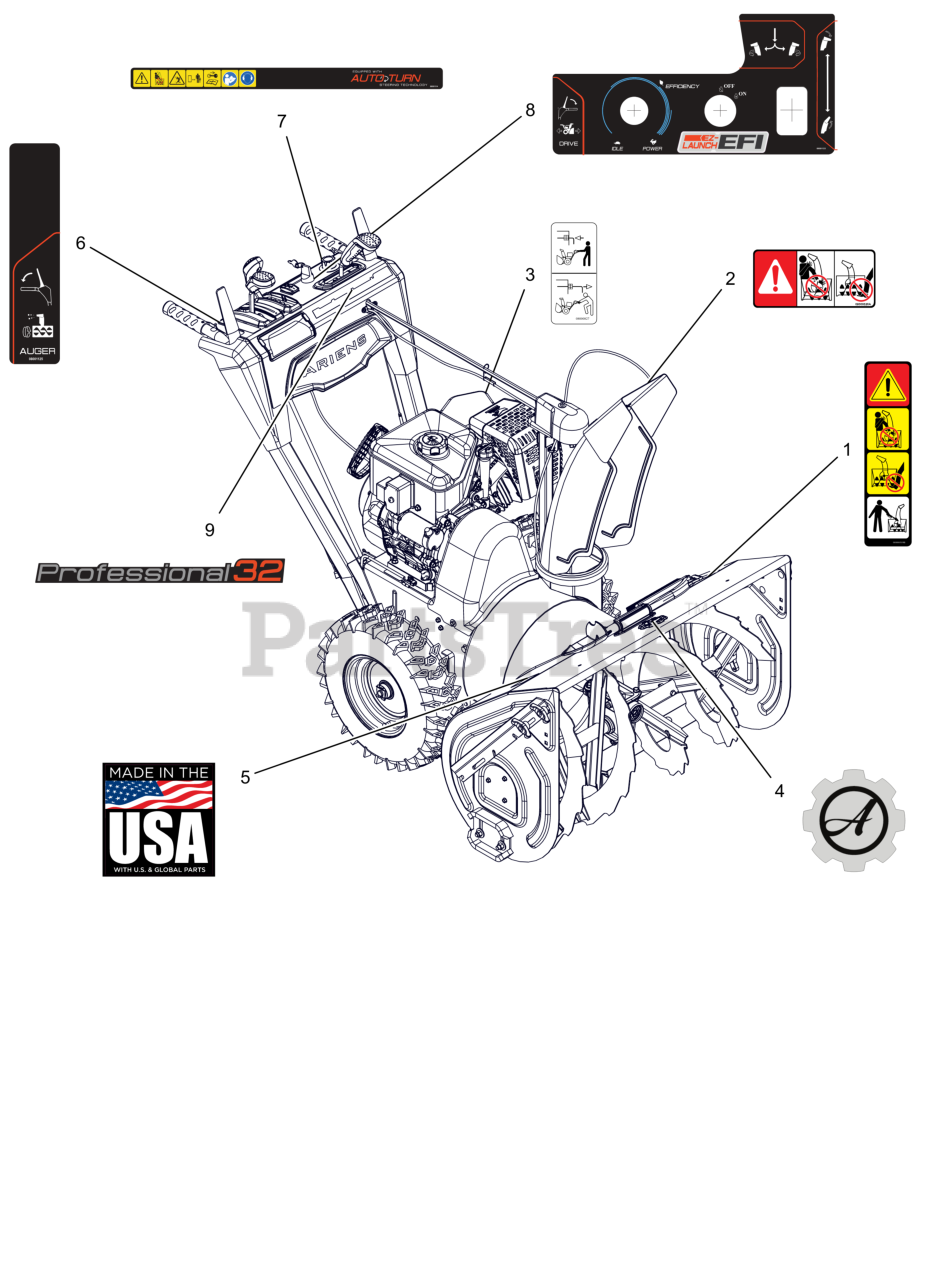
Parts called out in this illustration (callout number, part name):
1	DECAL, DANGER - ROTATING PARTS
2	DECAL, DANGER
3	DECAL, BYPASS
4	DECAL, ARIENS - GEAR BADGE
5	DECAL, MADE IN USA
6	DECAL,CONTROL-RH CONTROL
7	DECAL,DASH - SAFETY/EFI
8	DECAL, CONTROL - QT EFI W/GEL
9	DECAL, DASH - PRO 32
